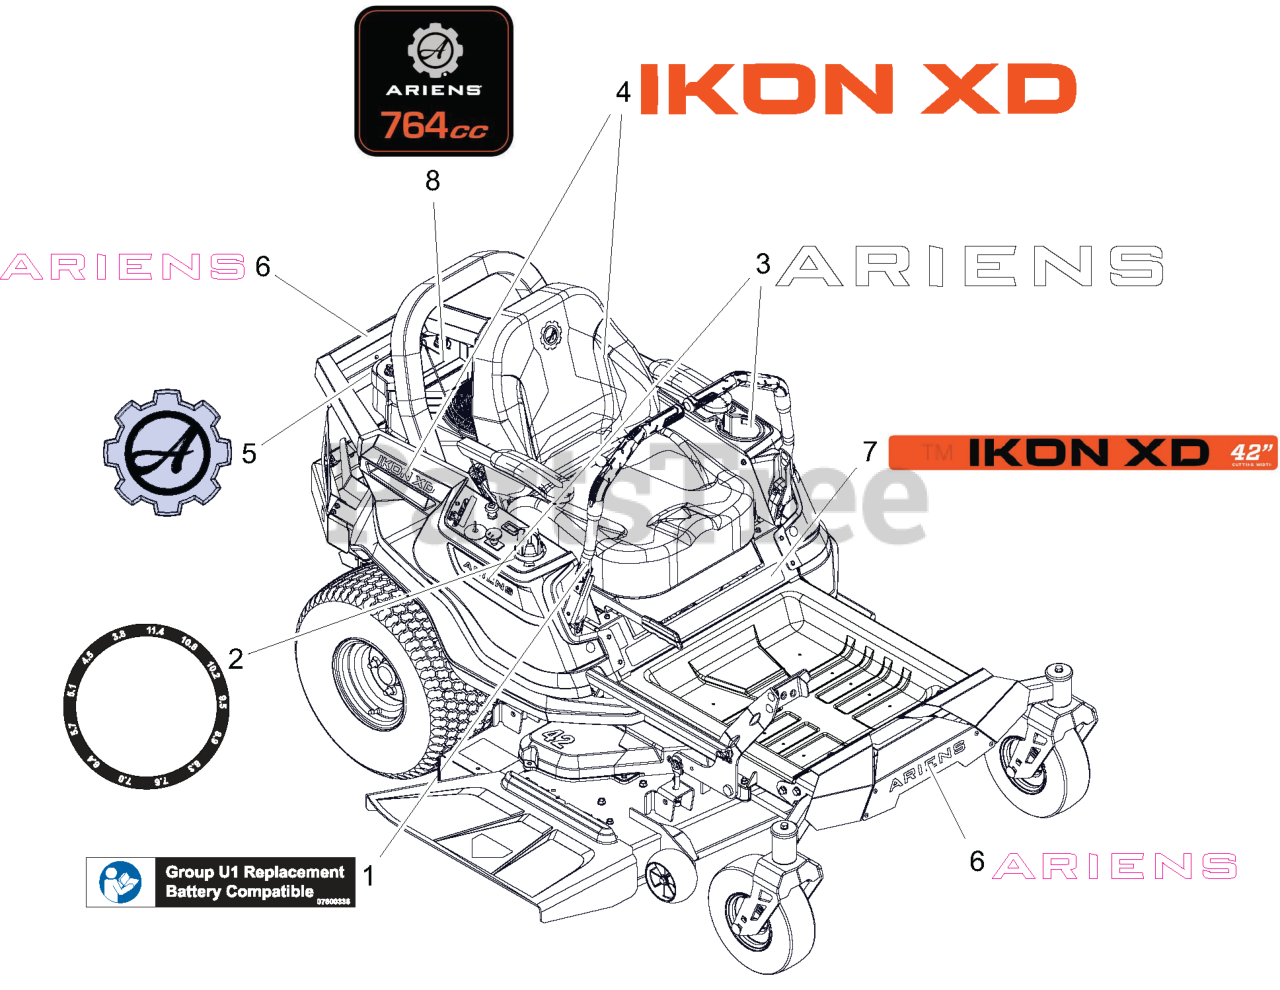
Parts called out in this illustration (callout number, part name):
1	DECAL, U1 BATTERY REPLACEMENT
2	DECAL, CUT HEIGHT - IKON CE
3	DECAL, ARIENS (6.50")
4	DECAL, FENDER - IKON XD
5	DECAL- ARIENS GEAR BADGE
6	DECAL - ARIENS 9.625"
7	DECAL, IKON XD - 42
8	DECAL - ARIENS 764 CC
